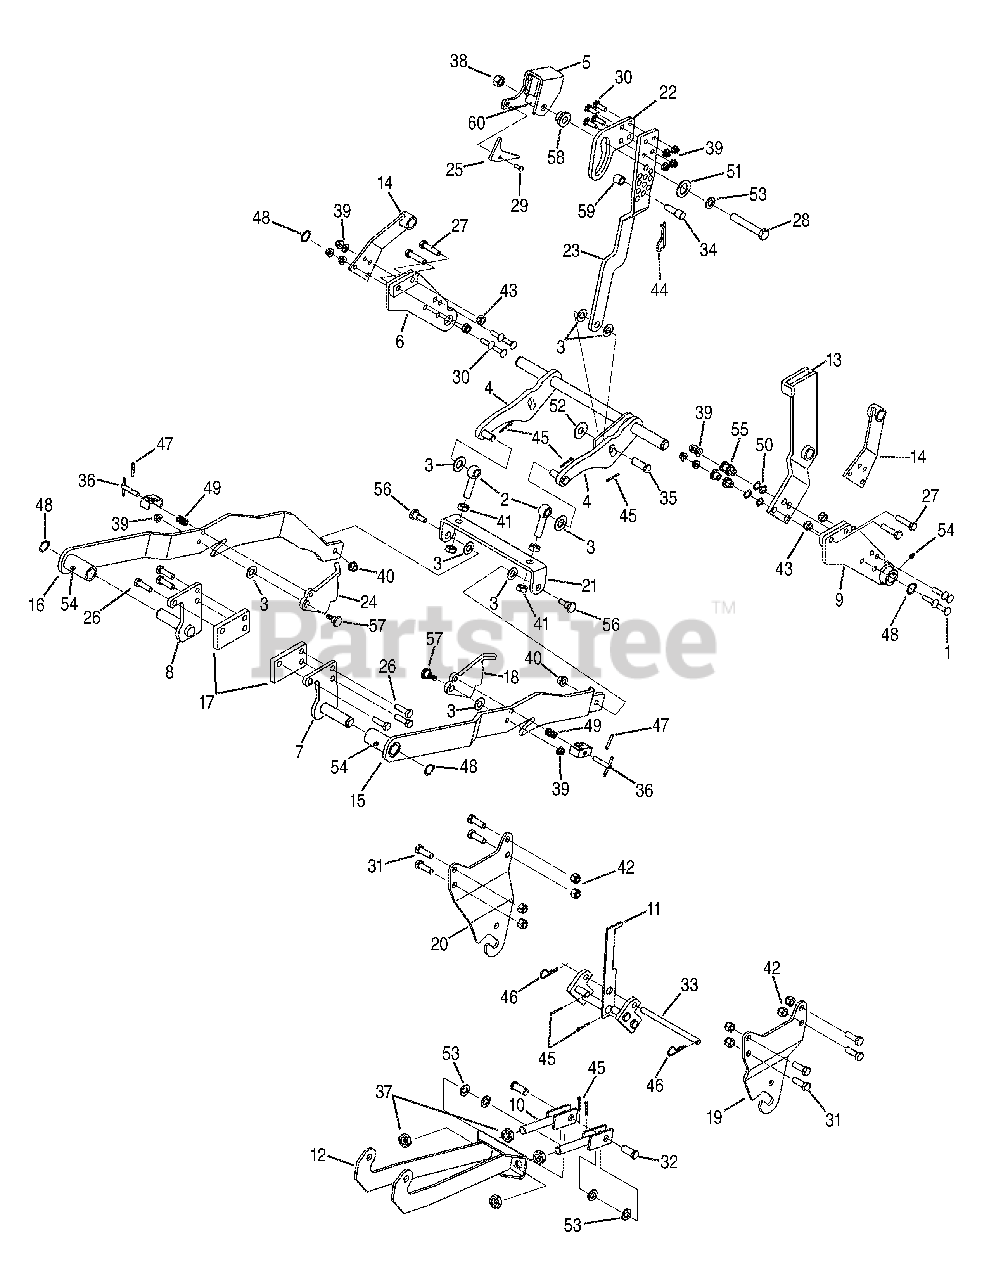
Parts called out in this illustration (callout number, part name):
1	Carriage Bolt, 3/8-16 x 1.50
2	Eye Bolt, 5/8-16 x 2.63
3	Flat Washer, 5/8
4	Rock Shaft Assembly
5	Lift Arm Bracket
6	RH Rock Shaft Mount Assembly
7	LH Deck Hanger Mount Assembly
8	RH Front Hanger Bracket
9	LH Rock Shaft Mount Assembly
10	Tension Rod Assembly Hanger
11	Tension Shaft Assembly
12	Front Tension Hanger Assembly
13	Height Stop Bracket
14	RH Shaft Stop Bracket
15	Left Rear Deck Hanger
16	Right Rear Deck Hanger
17	Bracket Hanger Spacer
18	LH Deck Latch
19	LH Front Hanger Bracket
20	RH Front Hanger Bracket
21	Lift Adjustment Link
22	Top Height Adjustment Link
23	Bottom Height Adjustment Link
24	RH Deck Latch
25	3-Point Bracket
26	Hex Screw, M12-1.75 x 40.0
27	Hex Screw, M12-1.75 x 50.0
28	Hex Screw, 5/8-18 x 4.0
29	Hex Screw, 1/4-20 x .75
30	Carriage Bolt, 3/8-16 x 1.25
31	Hex Screw, 1/2-13 x 1.50
32	Clevis Pin, .625 x 1.50
33	Front Hanger Pin
34	Height Adjustment Pin
35	Clevis Pin, .625 x 1.75
36	Latch Lock Pin
37	Jam Nut, 3/4-10
38	Hex Nut, 5/8-18
39	Flange Lock Nut, 3/8-16
40	Flange Lock Nut, 7/16-20
41	Jam Nut, 5/8-11
42	Hex Lock Nut, 1/2-13
43	Flange Lock Nut, M12-1.75
44	Internal Cotter Pin, .148 x 3.00
45	Cotter Pin, 5/32 x 1.25
46	Internal Cotter Pin
47	Spring Roll Pin, 3/16 x 1.5
48	Snap Ring, 1.0
49	Compression Spring, 0.63 x 1.00
50	Wave Washer, .625 x .885 x .015
51	Flat Washer, 1.00 x 1.75 x .107
52	Flat Washer, .635 x 1.589 x .060
53	Flat Washer, .640 x 1.12 x .125
54	Grease Fitting
55	Shoulder Spacer, .38 x 1.0 x.70
56	Shoulder Spacer, 7/16-20 x .625 x .500
57	Shoulder Screw, 3/8-16 x .625 x .442
58	Shoulder Spacer, 1.0 x .75
59	Spacer, .813 x .595 x .75
60	Spacer, .635 x .88 x 1.72
